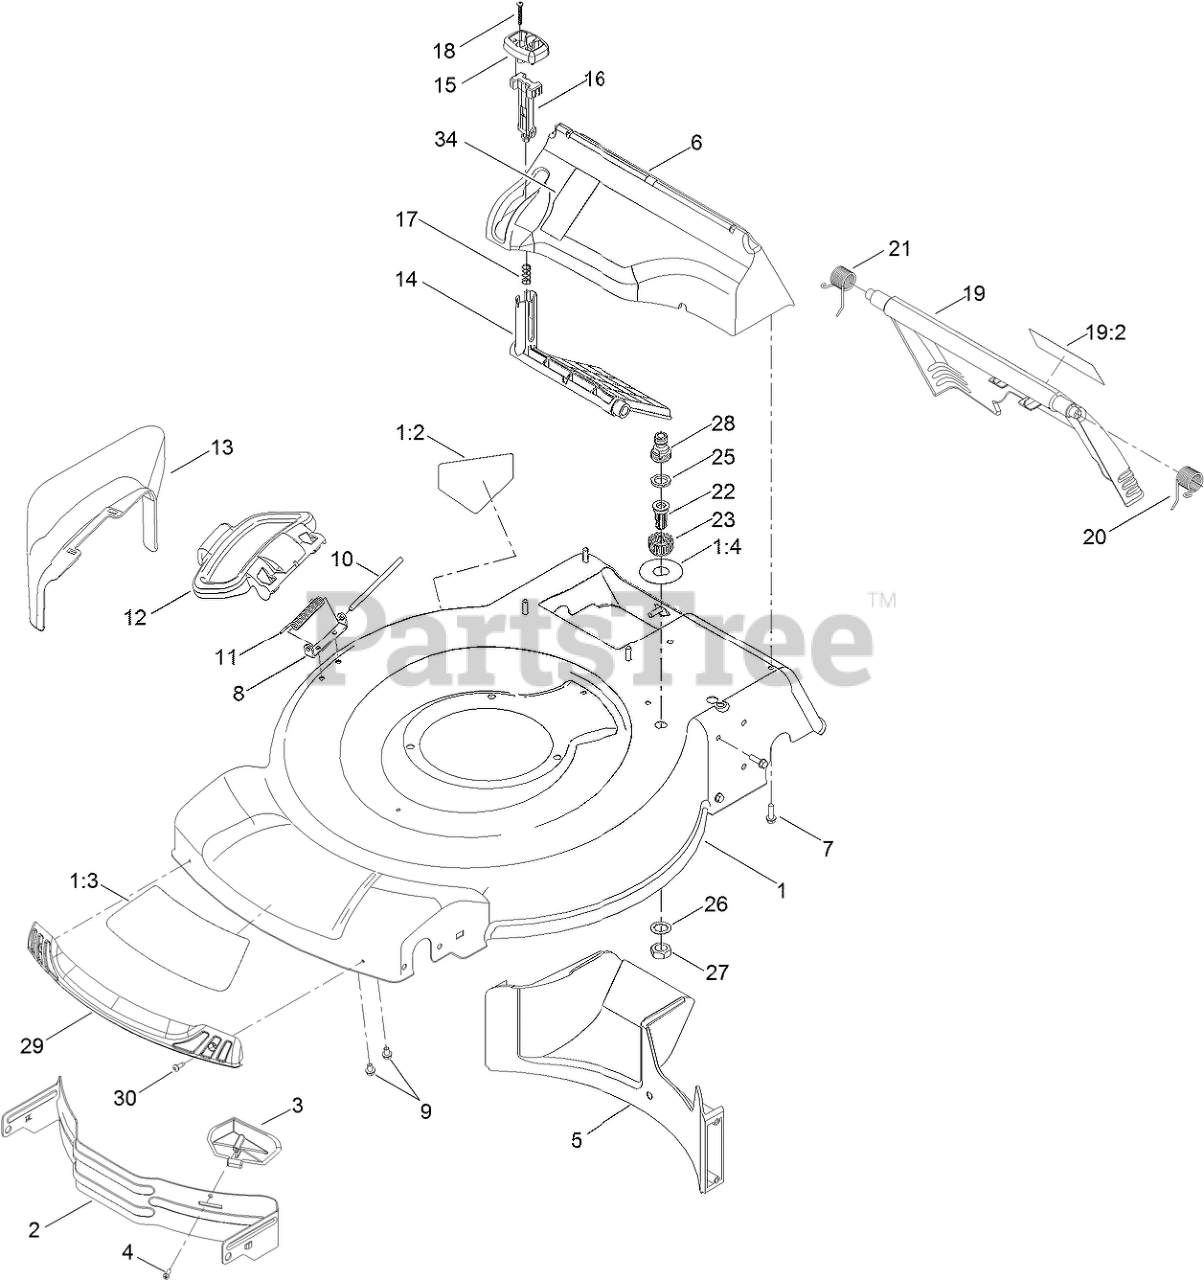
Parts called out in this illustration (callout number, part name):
1	HOUSING ASM
1:2	DECAL-DANGER
1:3	DECAL-RECYCLER
1:4	DECAL-PORT, WASHOUT
2	BAFFLE-FRONT
3	KICKER-FRONT
4	SCREW-PPH
5	BAFFLE-REAR
6	CHUTE-RECYCLE
7	SCREW-HWH
8	BRACKET-COVER
9	SCREW-HWH
10	ROD-COVER
11	SPRING-TORSION
12	DEFLECTOR-SIDE
13	CHUTE-DISCHARGE, SIDE
14	DEFLECTOR-RECYCLE
15	KNOB-RECYCLE
16	LATCH-RECYCLE
17	SPRING-COMPRESSION
18	SCREW-PPH
19	REAR DOOR ASM
19:2	DECAL-WARNING
20	SPRING-TORSION
21	SPRING-TORSION
22	PORT-WASHOUT
23	COUPLING-HOSE, WASHOUT PORT
25	WASHER-SEAL, WASHOUT PORT
26	WASHER-TOOTH, INTERNAL
27	NUT-JAM
28	ADAPTER-CONNECT, QUICK
29	BUMPER
30	SCREW-FORMING, THREAD
